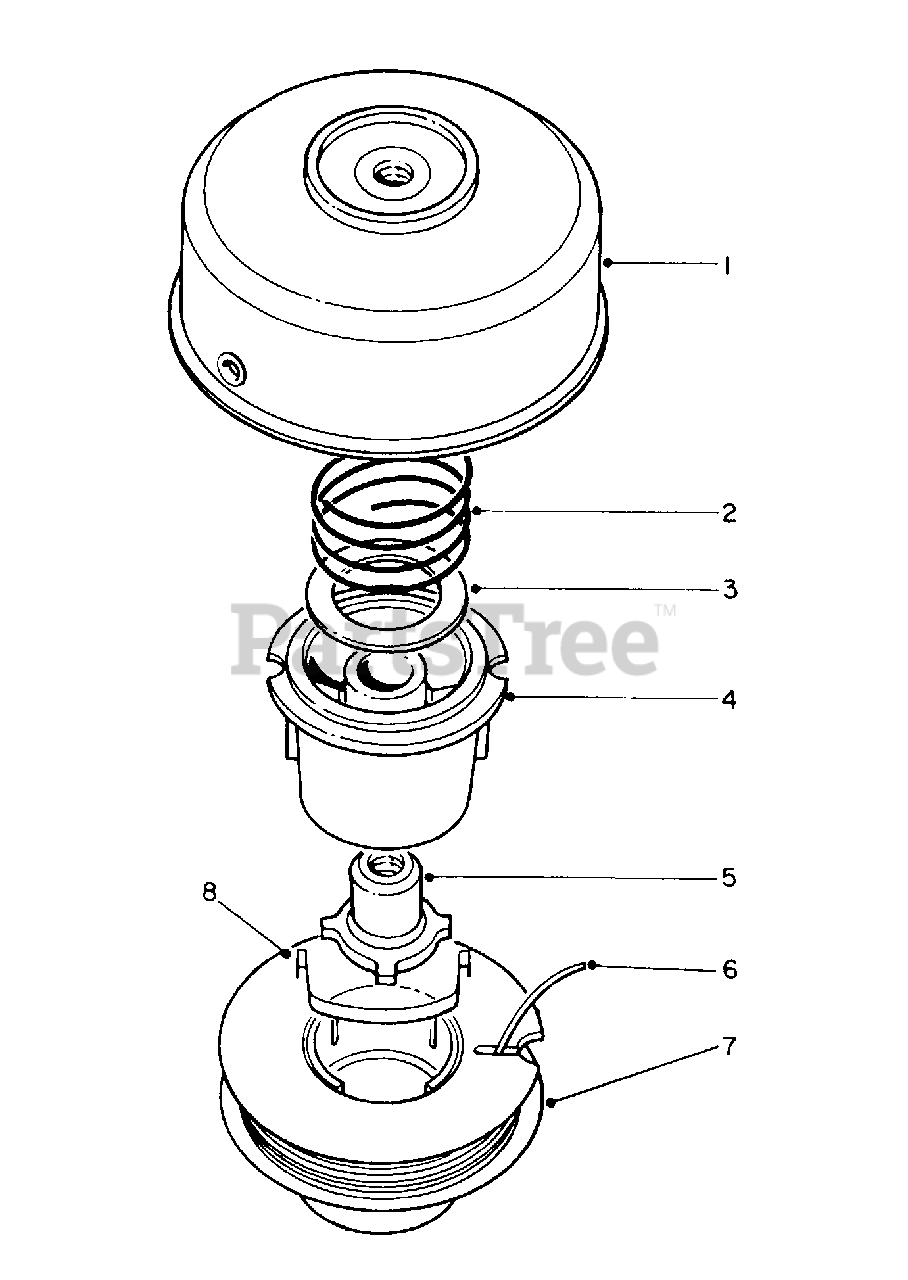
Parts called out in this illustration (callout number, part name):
1	Drum w/Eyelet
4	Core-Spool
5	Driver L.H.
6	Line-Cutting .095 Dia.
7	Spool Prewound .95 Dia. 30'(Incl. Ref. #8)
8	Saddle-Spool Cap
